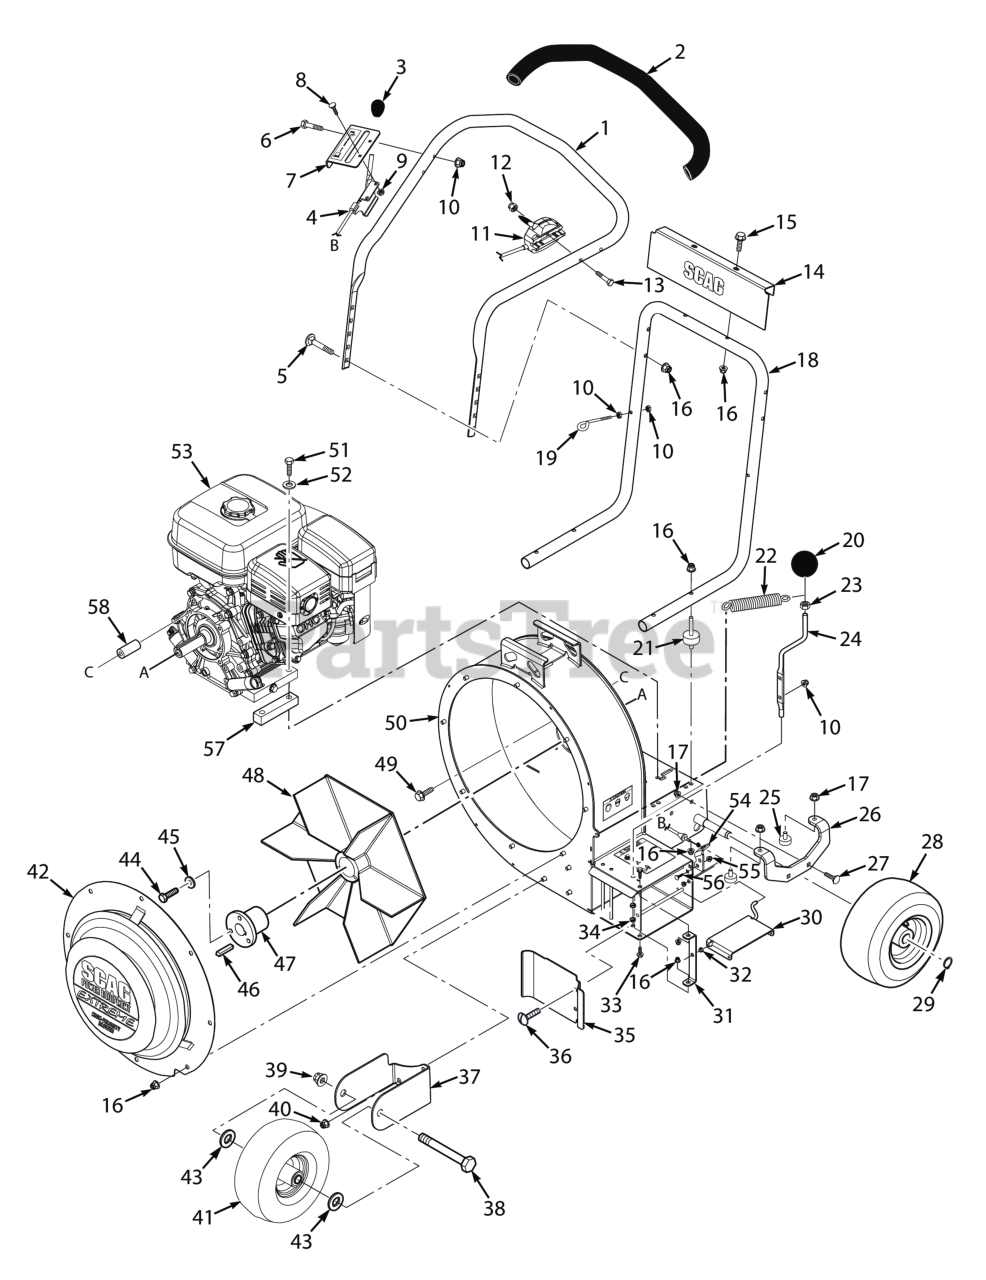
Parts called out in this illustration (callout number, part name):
1	Handle, Upper w/Grip (incl. #2)
2	Grip, 1" x 21-1/2"
3	Knob, Throttle
4	Control Cable, Air Direction (incl. #3)
5	CARR BOLT, 5/16-18 X 1.75
6	Bolt, Hex Head, 1/4-20 x 1-1/2"
7	Mounting Bracket, Control Plate w/Decal
8	Bolt, Carriage #10-24 x 1/2"
9	Nut, Elastic Stop #10-24
10	NUT, 1/4-20 SERRATED FLANGE HEX HEAD
11	Cable, Throttle Control (B&S BV10)
12	HEX, NUT, ELASTIC STOP LOCK, 1/4-20
13	Bolt, 1/4-20 x 2-1/2"
14	Handle Bar Cover w/Decal
15	Bolt, Serrated Flange Hex Head 5/16-18 x 1.50"
16	Nut, Flange Head Elastic Stop 5/16-18
17	Nut, Serrated Flange 5/16-18 (Right Front Engine Mounting, Briggs and Kohler Only)
18	Handle, Lower - LBX
19	Guide, Pull Rope
20	Knob, 3/8-16 Thread
21	Mount, Vibration
22	Spring, Air Discharge Door
23	HEX LOCKNUT, ELASTIC STOP, 3/8-16
24	Rod, Forward Air Control
25	Bumper, Rubber 5/16-18 x 5/8"
26	Bracket, Limiter Plate
27	Bolt, Carriage 5/16-18x1" (large frame units only)
28	Wheel Assembly, 4.10 x 3.5-6
28	Rim w/Valve
28	Bearing
29	RETAINING RING, 5/8 EXT. - BASIC
30	Door Weldment, Side Discharge Control
31	Pivot Bracket, Side Discharge
32	Bearing, .250 ID
33	Capscrew, 5/16-18 x .75 Serrated Flange Hex Head
34	Bearing, .375 ID
35	Door, Forward Air Control
36	Bolt, Carriage 1/4-20 x 1/2"
37	Caster Bracket, Extreme
38	BOLT, HEX HEAD, 5/8-11 X 5-1/2
39	HEX LOCKNUT, ELASTIC STOP, 5/8-11
40	Nut, Flange Elastic Stop Nut, 3/8-16
41	Wheel Assembly, 9 x 3.5-4
41	Rim w/Valve
41	Bearing
42	Baffle Assembly, Extreme w/Decal
43	Flatwasher, 5/8 - (..688 x 1.75 x .134)
44	Bolt, Hex Head 5/16-18 x 1-1/2" Grade 8
45	Lockwasher, 5/16 (.317 x .586 x .078) Helical Spring
46	Key, 1/4 x 1/4 x 2.0"
47	Tapered Hub, P2 SPCL - 1" Bore
48	Impeller Weldment, 15" Extreme -LBX
49	Bolt, Serr. Flng 5/16-24 x 3/4" (B&S)
49	Bolt, Serr. Flng 5/16-24 x 1-3/4" (Honda)
50	Housing Weldment, Extreme w/Decals
51	Bolt, Hex Head, 5/16-18 x 2.75 Zinc.
51	Bolt, Hex Head 3/8-16 x 1-3/4" (Kohler EFI)
52	Flatwasher, 5/16-.375 x .875 x .083 (35BV & 37BV-EFI)
52	Flatwasher, 3/8" Special (.391 x .938 x .105)
53	Engine, B&S BV10 (not avail through Scag)
53	Engine, Honda GX270 (not avail through Scag)
54	Bracket, Air Flow
55	Nut, Flanged Elastic Stop 1/4-20
56	Serr. Fl. Hex Head CPSCR, 1/4-20 x 3/4"
57	Spacer, Engine (B&S Engine Only)
58	Spacer (excludes SVRII-36A)
